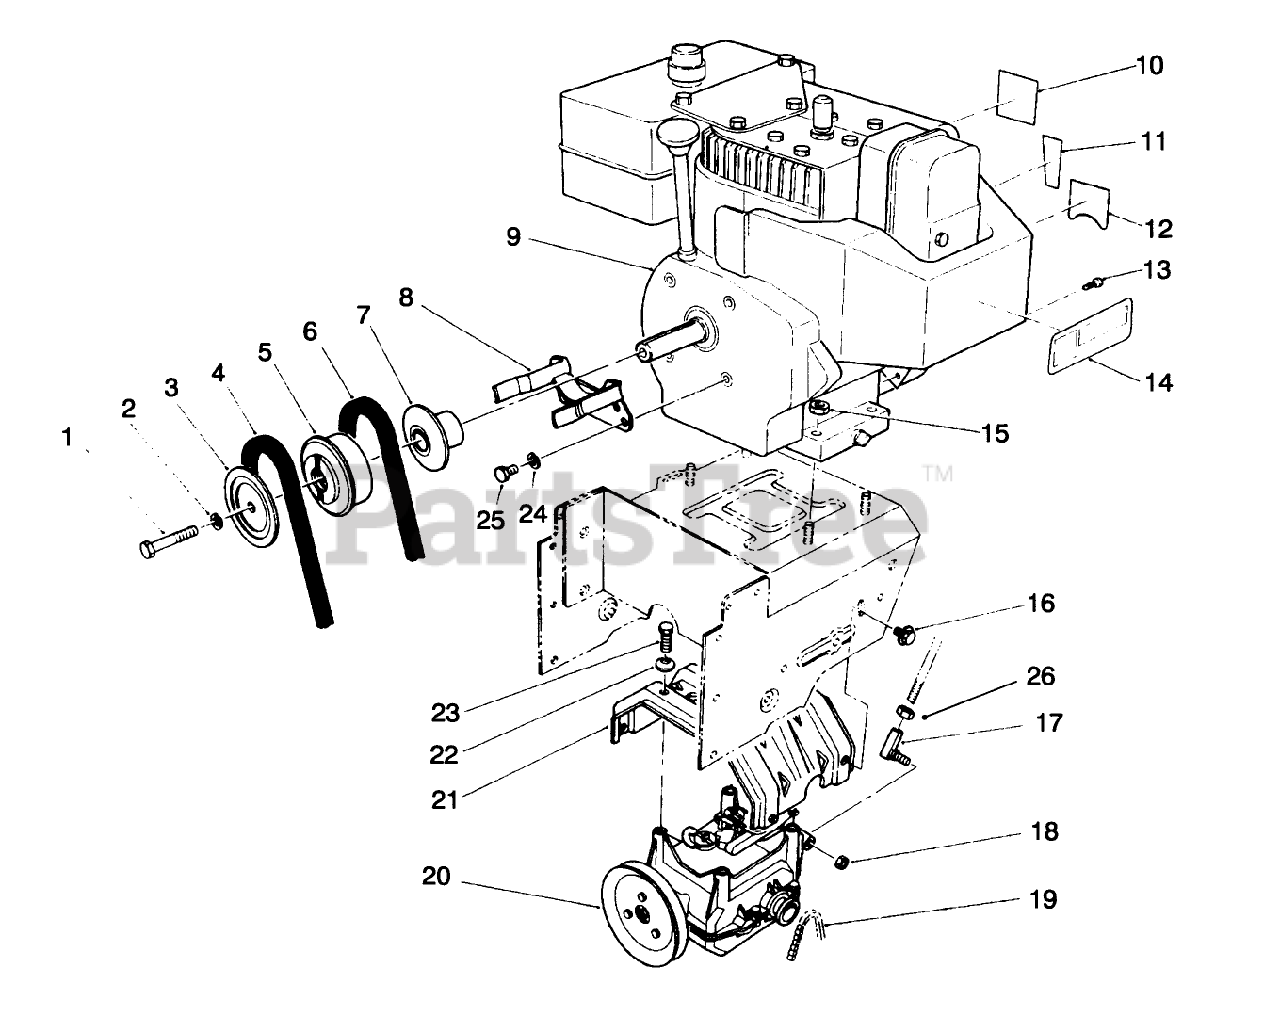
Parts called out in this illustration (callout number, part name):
1	SCREW-HH
2	WASHER-LOCK
3	SHEAVE-HALF, IMPELLER
4	V-BELT
5	PULLEY-ENGINE, CENTER
6	V-BELT-TRACTION
7	SHEAVE-HALF, TRACTION
8	Guide-Belt
9	Engine
10	DECAL-PRIMER
11	DECAL-THROTTLE
12	DECAL-CHOKE
13	SCREW-HWH
14	DECAL-WARNING, HOT SURFACE
15	NUT-HF
16	SCREW-HHF
17	JOINT-BALL
18	NUT-LOCK, NI
19	CHAIN
20	TRACTION GEARCASE ASM
21	Frame-Transmission
22	WASHER-SPRING
23	SCREW-HWHTF
24	WASHER-LOCK
25	SCREW-HH
26	NUT-HJ
